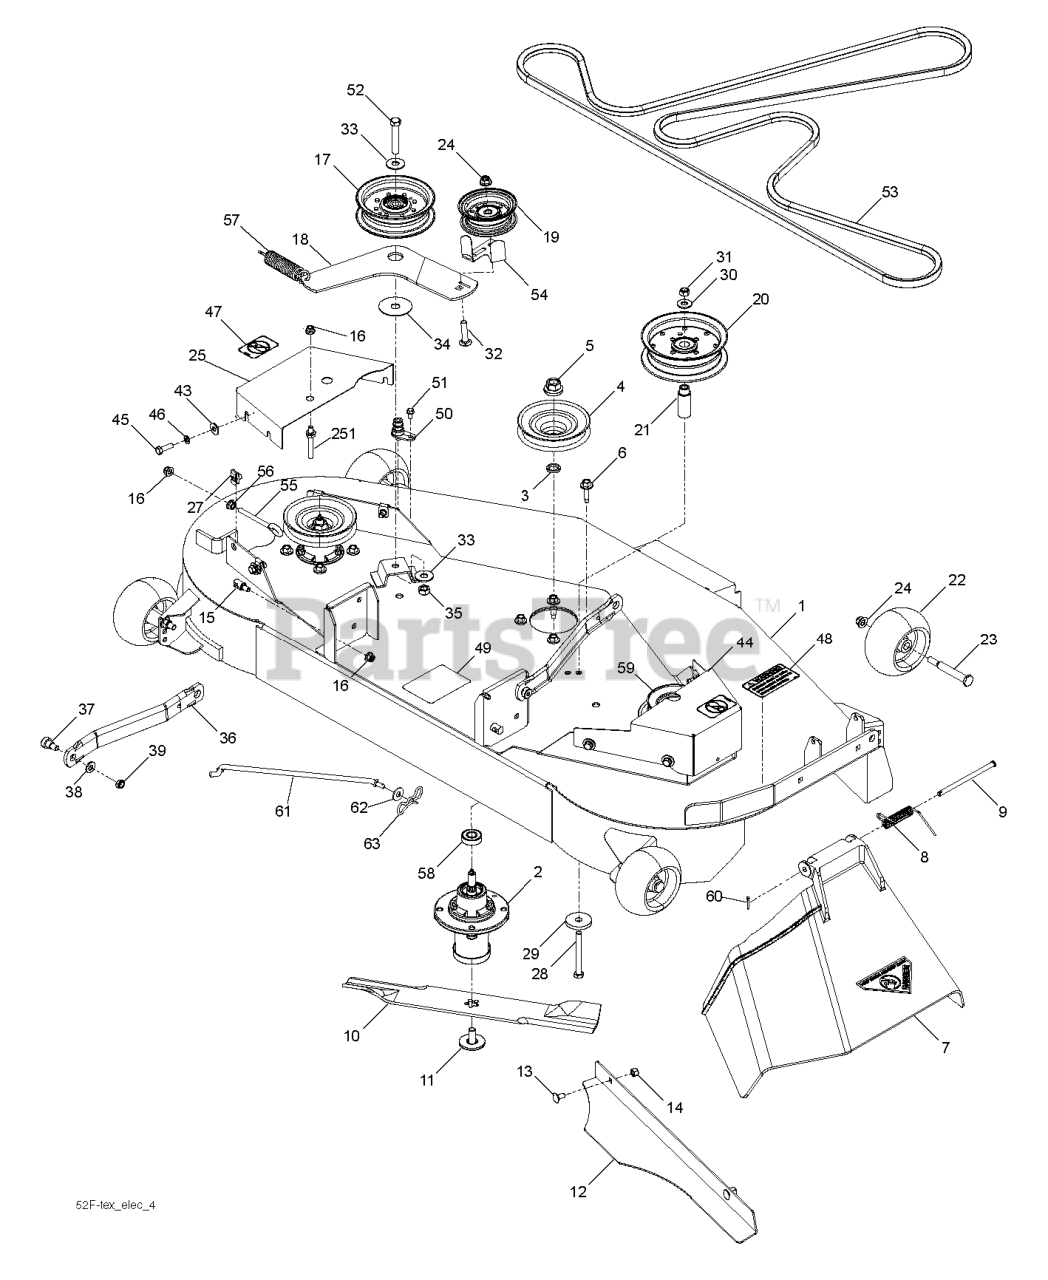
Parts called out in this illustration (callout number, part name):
1	DECK SVC W/DECALS.52.GTH.ORG
2	MANDREL.DECK.ASSEMBLY
3	WASHER.SPACER.MANDREL
4	PULLEY.DRIVEN.DECK.48'
5	NUT.FLANGE.LOCK.TOP
6	SCREW, WASHER HEAD
7	DISCHARGE CHUTE 52"
8	SPRING - TORSION
9	PIN-CLEVIS 5/16 DIA X 5.19 ZD
10	BLADE, 17.75 X 2.5 X .25
11	BOLT.WASHER.ASM.7/16-2
12	PLATE.52".CONFINEMENT.BLACK
13	BOLT.CARR.5/16-18X5/8.SHORT
14	NUT.71038.31-18.HEX.NYLOCK
15	STUD.FASTNER.W/ANTI-ROTATE
16	5/16-18 NYLOC FLANGE NUT
17	PULLEY.IDLER.MWR.STATI.LH
18	ARM, IDLER, 52" BLK
19	PULLEY.IDLER.FLAT
20	PULLEY, IDLER
21	BUSHING, IDLER
22	GAUGE WHEEL
23	BOLT.SHOULDER.3/8-16X3-5/8.
24	NUT 3/8-16 HEX FLG NYLOC ZD
25	SHIELD.BELT.LH.ORANGE
27	U-CLIP 5/16-18 NUT RETAINER
28	HCS 3/8-16 X 3-1/2 GR5 ZD
29	SPINDLE WASHER
30	RP WASHER 3/8 FLAT
31	NUT 3/8-16 NYLOC
32	RHSNB 3/8-16X1-3/4
33	WASHER 7/16 FLAT ZD
35	NUT 7/16-14 HEX WHIZ LK SMOOTH
36	ARM.SUSPENSION.MOWER
37	SB 3/8-16 X 3/8 SKT HD ZD
38	WASHER
39	NUT HEX 3/8-16 NYLON, THIN
43	WASHER 5/16 FLAT
44	SHIELD.BELT.RH.52.ORANGE
45	BOLT.FIN.HEX.5/16-18UNC X 1.00
46	WASH.5/16.SLW.ZD
47	DECAL, NO STEP
48	DECAL, CAUTION
49	DECAL.MOWER.SCH.48/54
50	PORT.WASHOUT
51	SCREW
52	BOLT.HEX.7/16-14
53	BELT, 143.5" EL
54	GUARD, BELT
55	EYE BOLT 5/16 X 3.50
56	NUT 5/16C WHIZ
58	BEARING, BALL
59	RP PULLEY, COLLECTION 48
60	RETAINER CLIP
61	ROD.ANTI.SWAY.48/54"K4
62	WASHER
63	PIN.COTTER.5/16.BOW TI
251	KEEPER,DRIVE BELT
